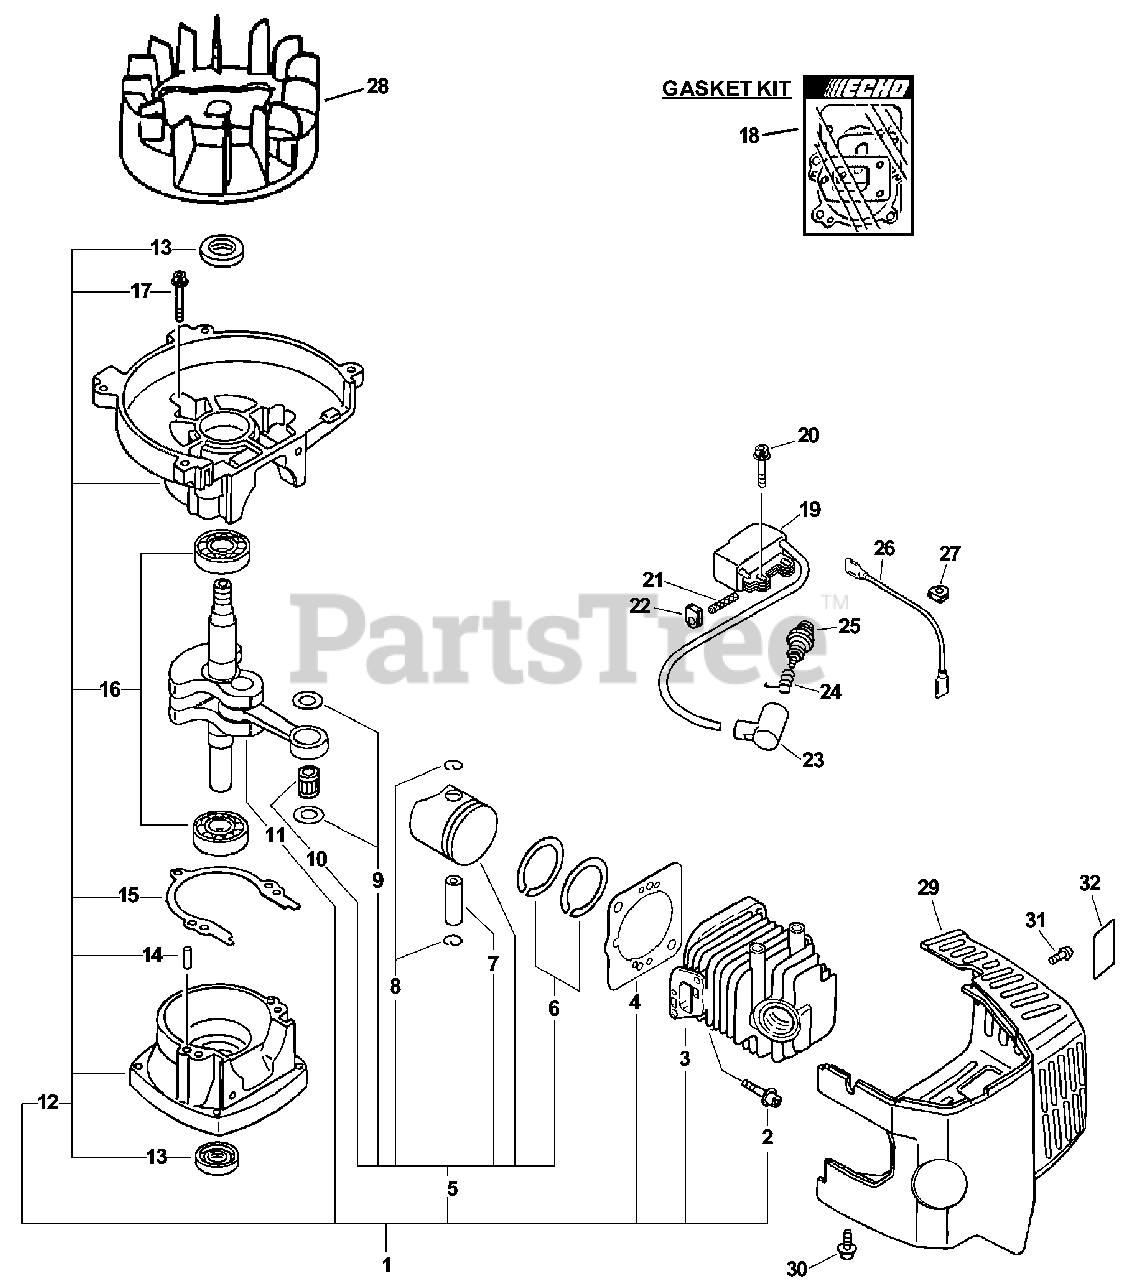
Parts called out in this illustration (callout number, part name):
1	SHORT BLOCK
2	BOLT 5×22
3	CYLINDER
4	GASKET, CYLINDER
5	PISTON KIT
6	RING, PISTON
7	PIN, PISTON 8
8	RING, SNAP
9	WASHER, THRUST
10	BEARING, NEEDLE
11	CRANKSHAFT ASSY
12	CRANKCASE KIT
13	SEAL, OIL 12
14	PIN, LOCATING 4
15	GASKET, CRANKCASE
16	BEARING, BALL - 6201 C3
17	BOLT 5×28
18	GASKET KIT
19	COIL, IGNITION
20	BOLT 4×20
21	TUBE, INSULATOR
23	CAP, SPARK PLUG
24	TERMINAL, SPARK PLUG
25	SPARK PLUG - BPM8Y
25	SPARK PLUG - BPMR8Y
26	LEAD
28	FLYWHEEL
29	COVER, ENGINE
30	BOLT 4×20
31	BOLT 4×8
32	LABEL, CAUTION - HOT
